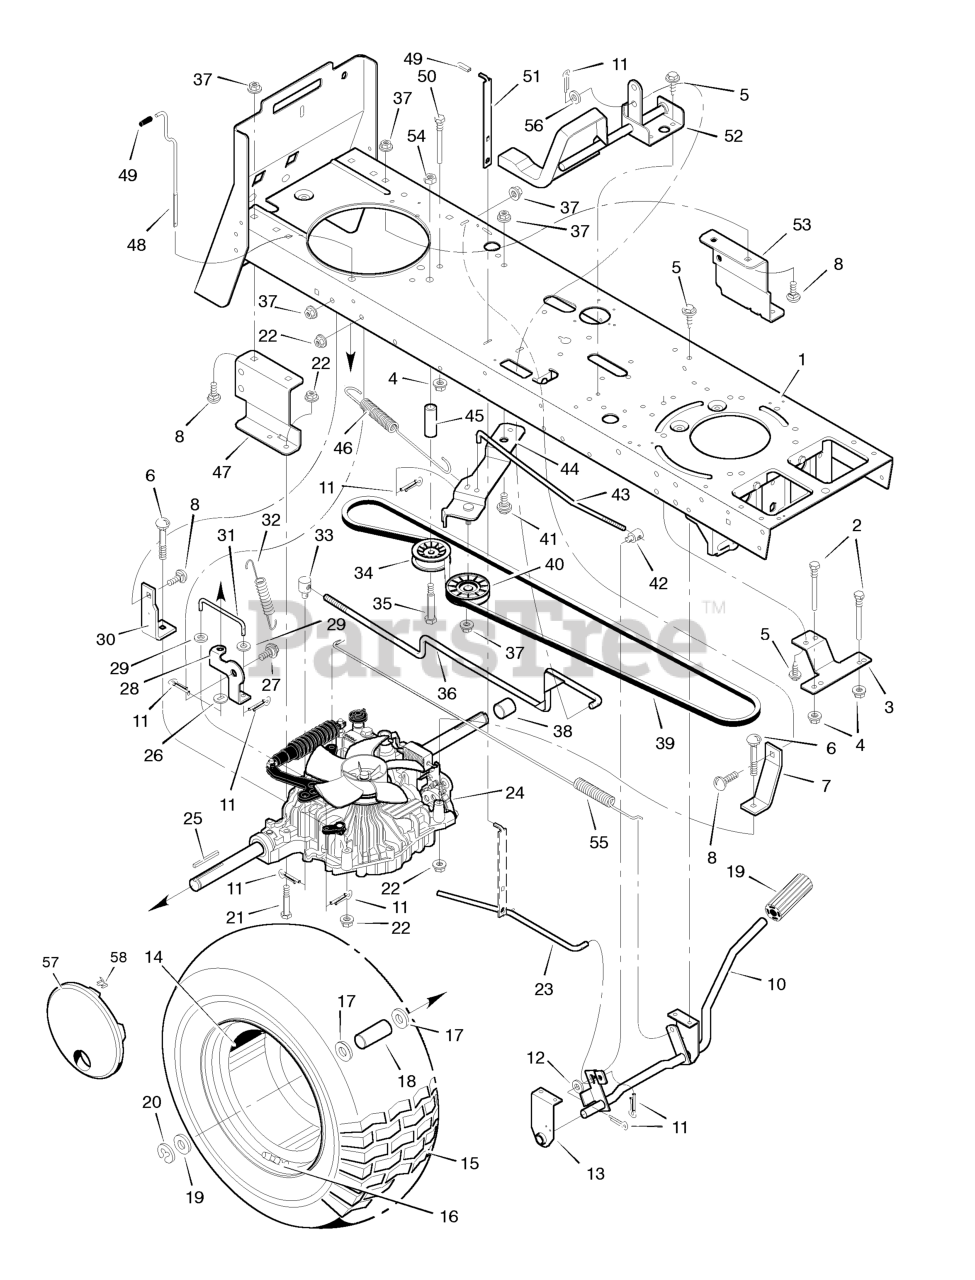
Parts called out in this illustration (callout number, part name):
1	Frame Assembly
2	Guide, Belt
3	Bracket, Belt Guide
4	Nut, Flange
6	Bolt, Carriage
7	Bracket, Torque
8	Bolt, Carriage
9	Pedal
10	Lever Assembly, Pedal
11	Pin, Cotter
12	Washer
13	Support, Pedal
14	Wheel and Tire Assembly
15	Tire *
16	Valve Stem
17	Washer
18	Spacer
19	WASHER, 1-1.3 16G FLT
21	Bolt, Hex
22	Nut
23	Rod, Latch
24	Transaxle
25	Key, Square
27	Bolt, Shoulder
28	Bracket, Dump Valve
29	Washer
30	Bracket, Torque
31	Rod, Dump Valve
32	Spring, Extension
33	NUT, Adjusting, 1/2-13
34	Pulley, Idler
35	Bolt, Hex
36	Rod, Control
37	Nut
38	Spacer
40	Pulley, Idler
41	Bolt, Shoulder
42	Nut, Adjusting
43	Rod, Clutch
44	Bracket, Idler
45	Spacer
46	Spring, Extension
47	Bracket, Right Transaxle
48	Rod, Dump Valve
50	Guide, Belt
51	Lever, Parking Brake
52	Pedal Assembly
53	Bracket, Left Transaxle
57	Disc, Wheel
58	Clip, Retainer
